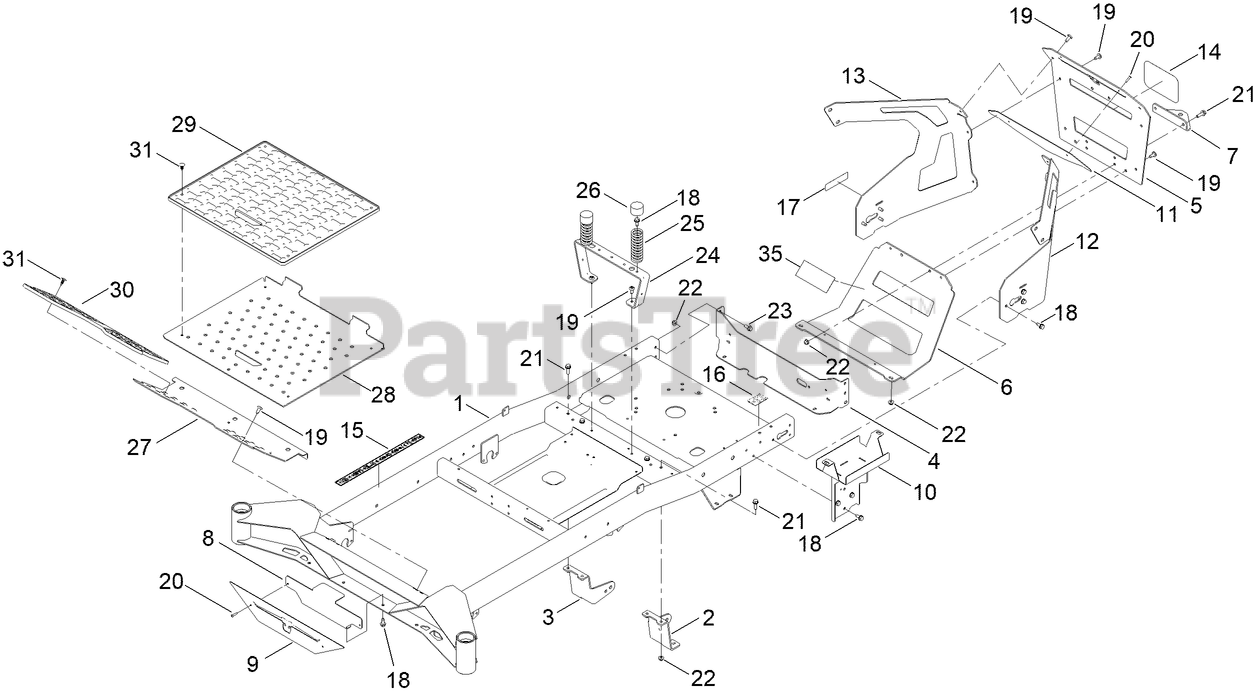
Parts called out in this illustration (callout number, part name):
1	SERVICE ASM-FRAME, TITAN
2	MOUNT-DRIVE, LH
3	MOUNT-DRIVE, RH
4	PLATE-MOUNT, REAR
5	GUARD-ENGINE
6	GUARD-MUFFLER
7	BRACKET-HITCH
8	PLATE-BACKER
9	LOGO-PLATE-FRONT
10	WA-BATTERY MOUNT
11	PLATE-BACKER
12	GUARD-ENGINE LH
13	GUARD-ENGINE-RH
14	DECAL
15	DECAL-WARNING
16	DECAL-BYPASS
17	DECAL-SPARK ARRESTER
18	SCREW-HWHTF
20	RIVET-TRIFOLD
21	SCREW-HHF
22	NUT-HF
23	SCREW-HHF
24	SUPPORT-SEAT
25	SPRING-COMPRESSION
26	CAP-PROTECTOR
27	PAN-FLOOR
28	PAN-FLOOR
29	FLOOR MAT
30	FLOOR MAT - TITAN
31	PLUG-PLASTIC
35	TAPE-HEAT
